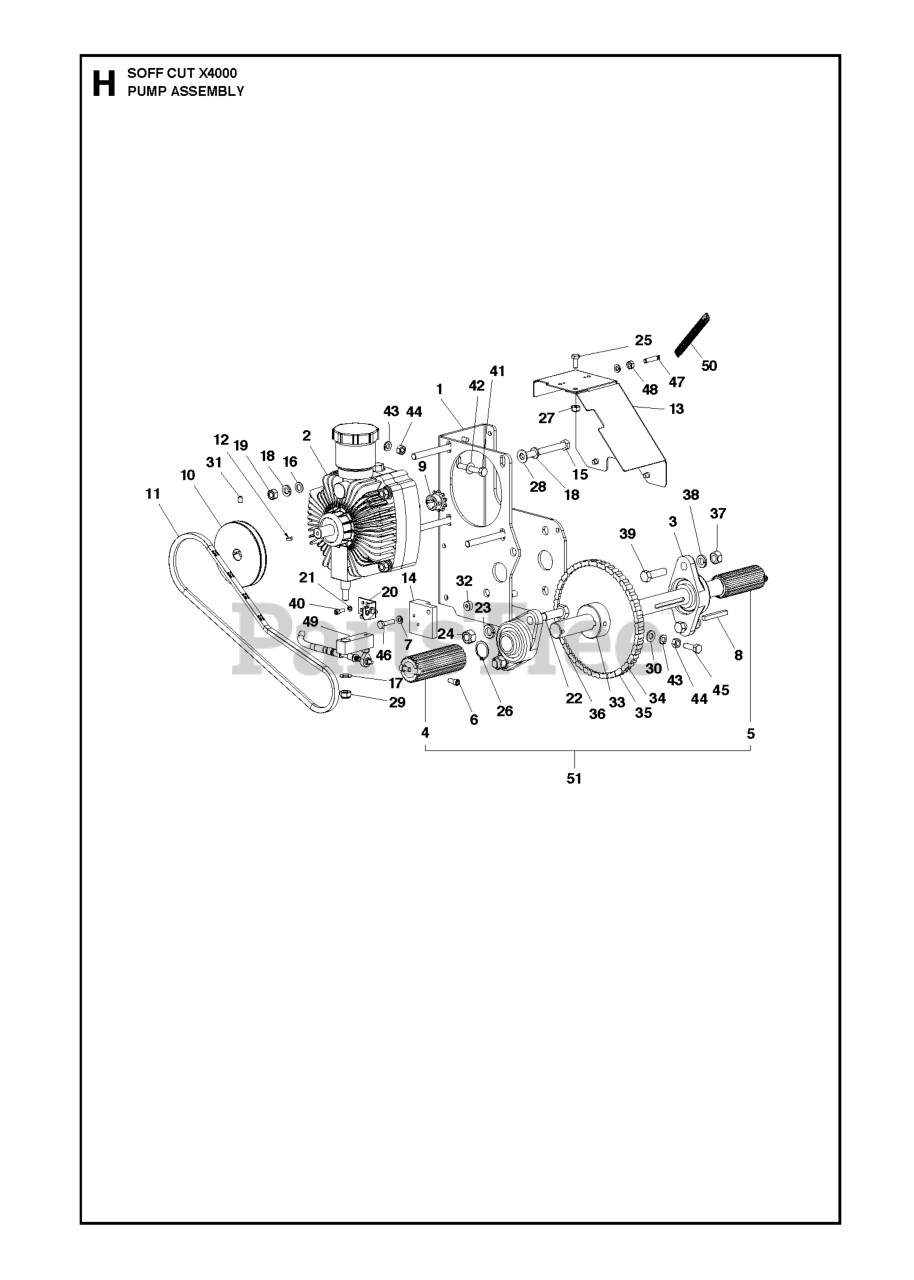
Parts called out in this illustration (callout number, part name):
2	HYDROSTATIC PEDAL ASSY
27	NUT
29	NUT
30	WASHER
33	SHC 10-24 X 1 1/4 STAINLESS S
45	HEX BOLT 5/16-18-1 CAD GR 5
